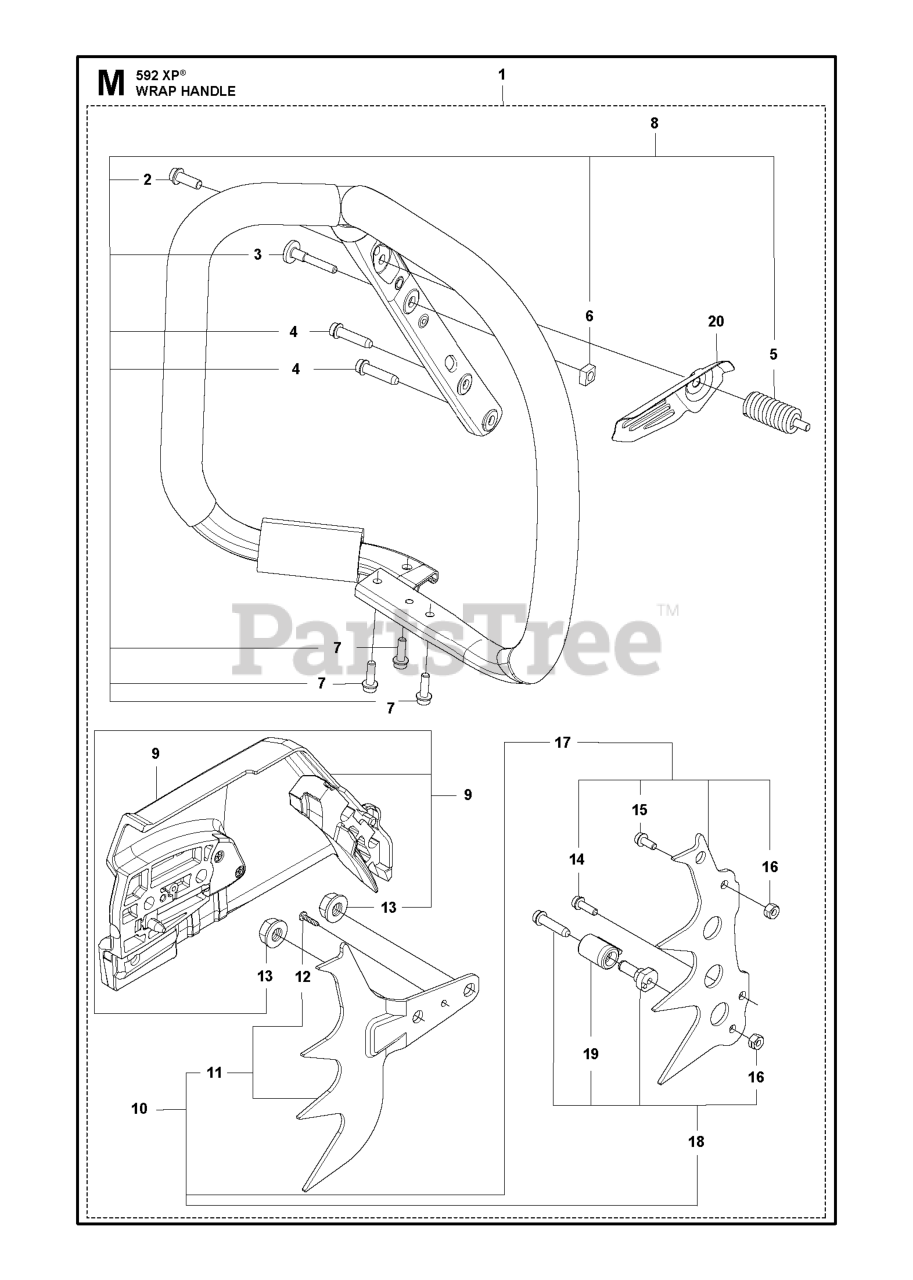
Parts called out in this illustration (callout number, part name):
1	WRAP KIT WITH COVER
2	SCREW ITXSCFM
3	SCREW ITXPANM MOVEMENT LIMITER
5	ANTIVIBRATION ELEMENT CYLINDE
8	HANDLE SYSTEM WRAP
9	Covers
10	SPIKE KIT WRAP
11	SPIKE KIT OUTER WRAP
12	SCREW CITXPANT
13	NUT M8 FLANGE
15	SCREW
17	SPIKE KIT INNER WRAP
18	CHAIN CATCHER H565/H572 KIT
